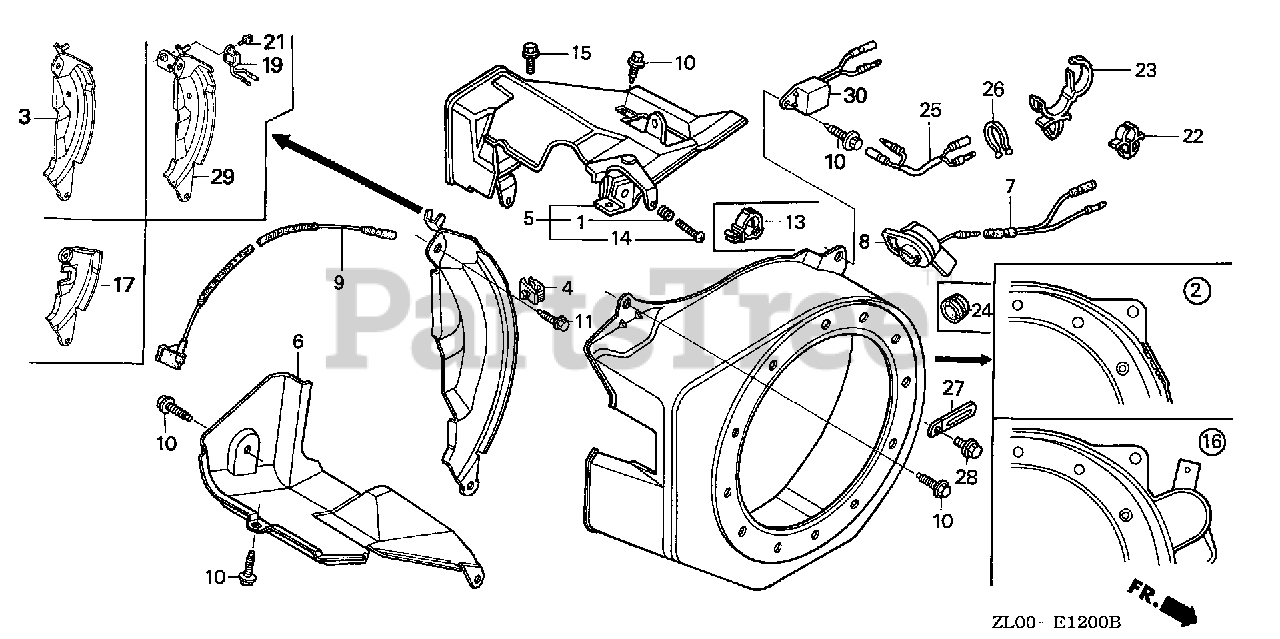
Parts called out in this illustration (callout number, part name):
2	COVER, FAN *NH246* (LOOSY GRAY)
2	COVER, FAN *R280* (POWER RED)
3	PLATE, SIDE (STD)
4	CLAMP, CORD
7	SUB-HARNESS
8	SWITCH ASSY., ENGINE STOP
9	WIRE, STOP SWITCH (370MM)
10	BOLT, FLANGE (6X12) (CT200)
11	BOLT, FLANGE (6X20) (CT200)
